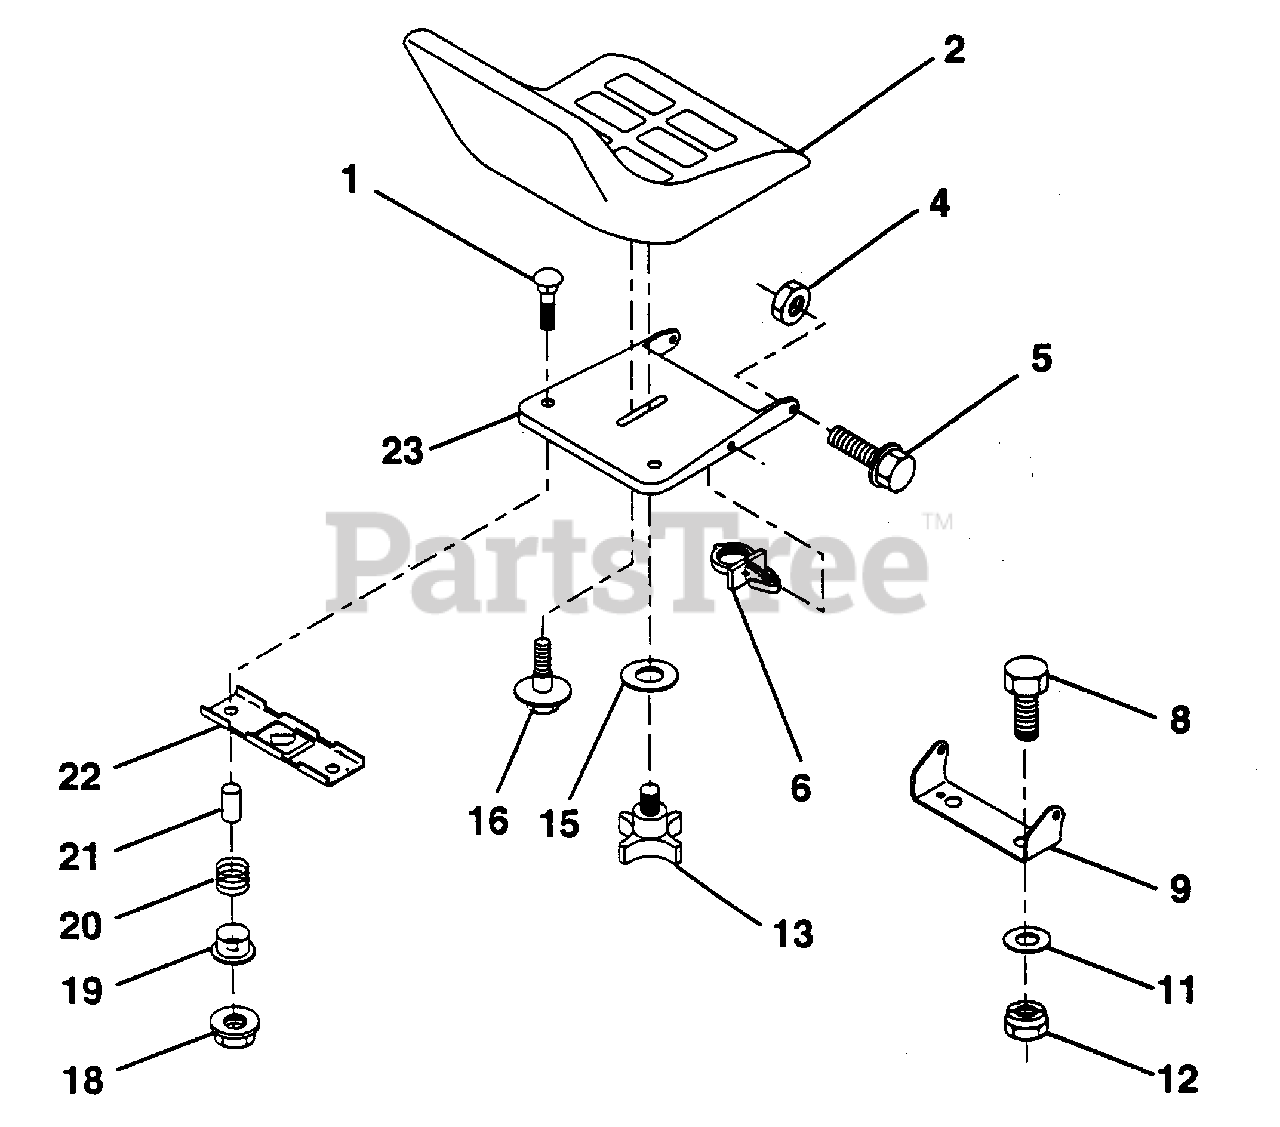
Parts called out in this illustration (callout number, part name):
1	Bolt, Carriage 1/4-20 x 1-3/8
2	Seat (AYP part number)
4	Nut Lock Hex W/Ins 5/16-18 (AYP part number)
5	Bolt, Shoulder 5/16-18 UNC (AYP part number)
6	Clip, Insulated (AYP part number)
8	Bolt, Hex, Fin. 3/8-16 UNC x 1 (AYP part number)
9	Bracket, Pivot, Seat (AYP part number)
11	Washer 12/32 x 2 x 10 Gauge (AYP part number)
12	Nut Lock Hex W/Wsh 3/8-16 (AYP part number)
13	Knob, Seat (AYP part number)
15	Washer 17/32 x 1-3/16 x 12 Gauge (AYP part number)
16	Bolt, Shoulder (AYP part number)
18	Nut, Hex, Large, Flange Lock (AYP part number)
19	Bushing, Snap (AYP part number)
20	Spring, Compression (AYP part number)
21	Spacer, Split, Large .28 ld. x .96 (AYP part number)
22	Bracket, Switch Mounting (AYP part number)
23	Pan, Seat (AYP part number)
